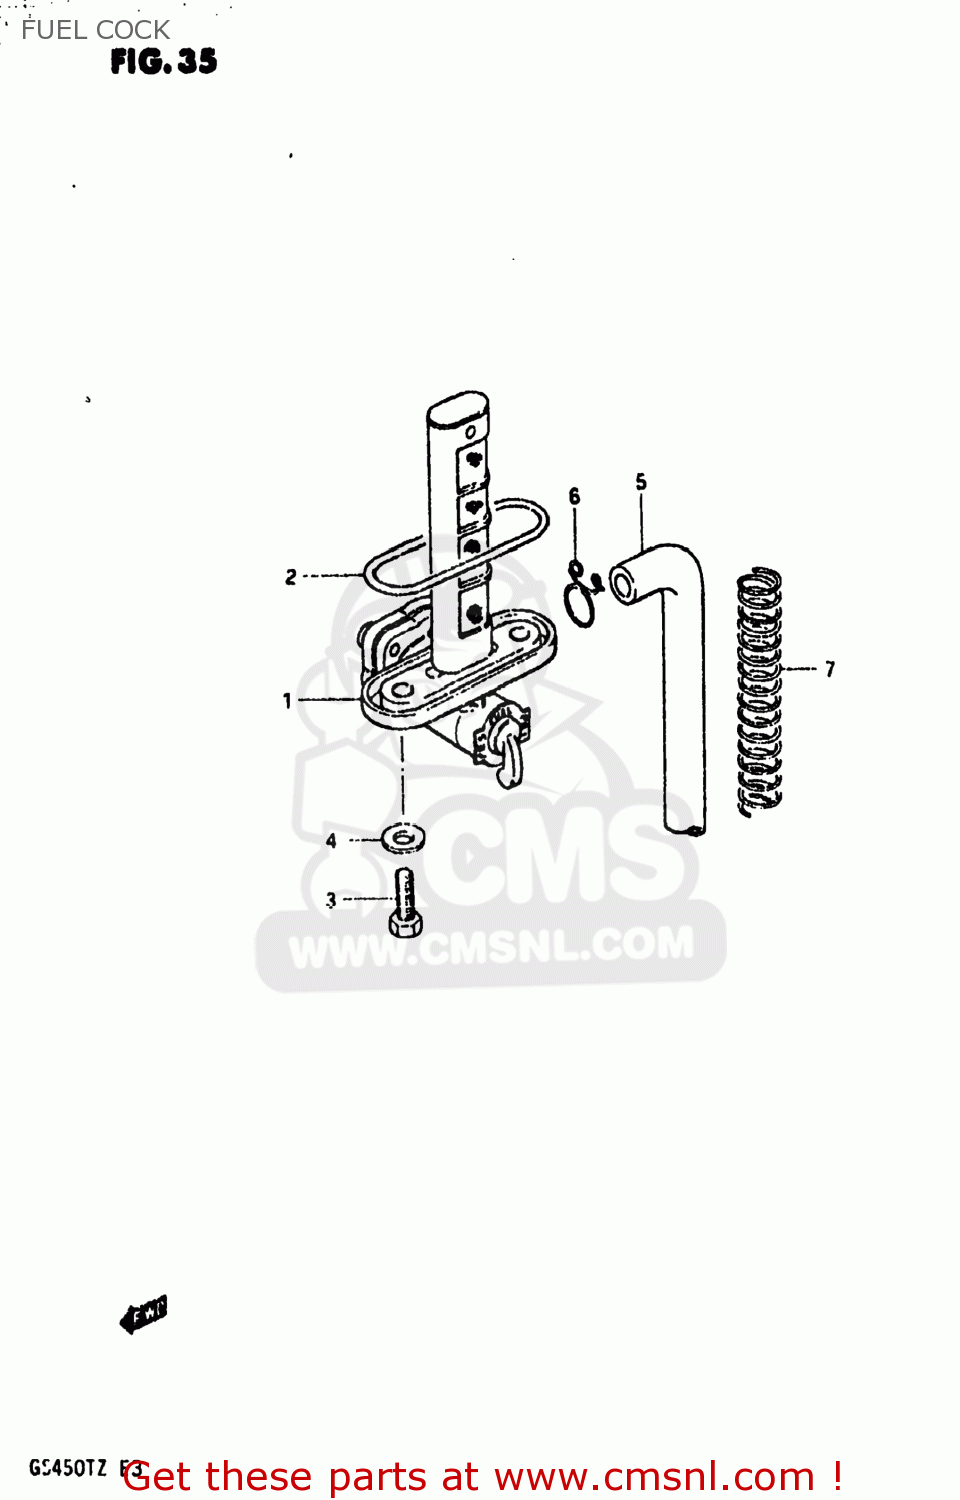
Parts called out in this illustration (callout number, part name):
1	COCK ASSEMBLY,FUEL
2	O RING
3	BOLT(6X20)
4	GASKET
5	HOSE
6	CLIP
7	SPRING
